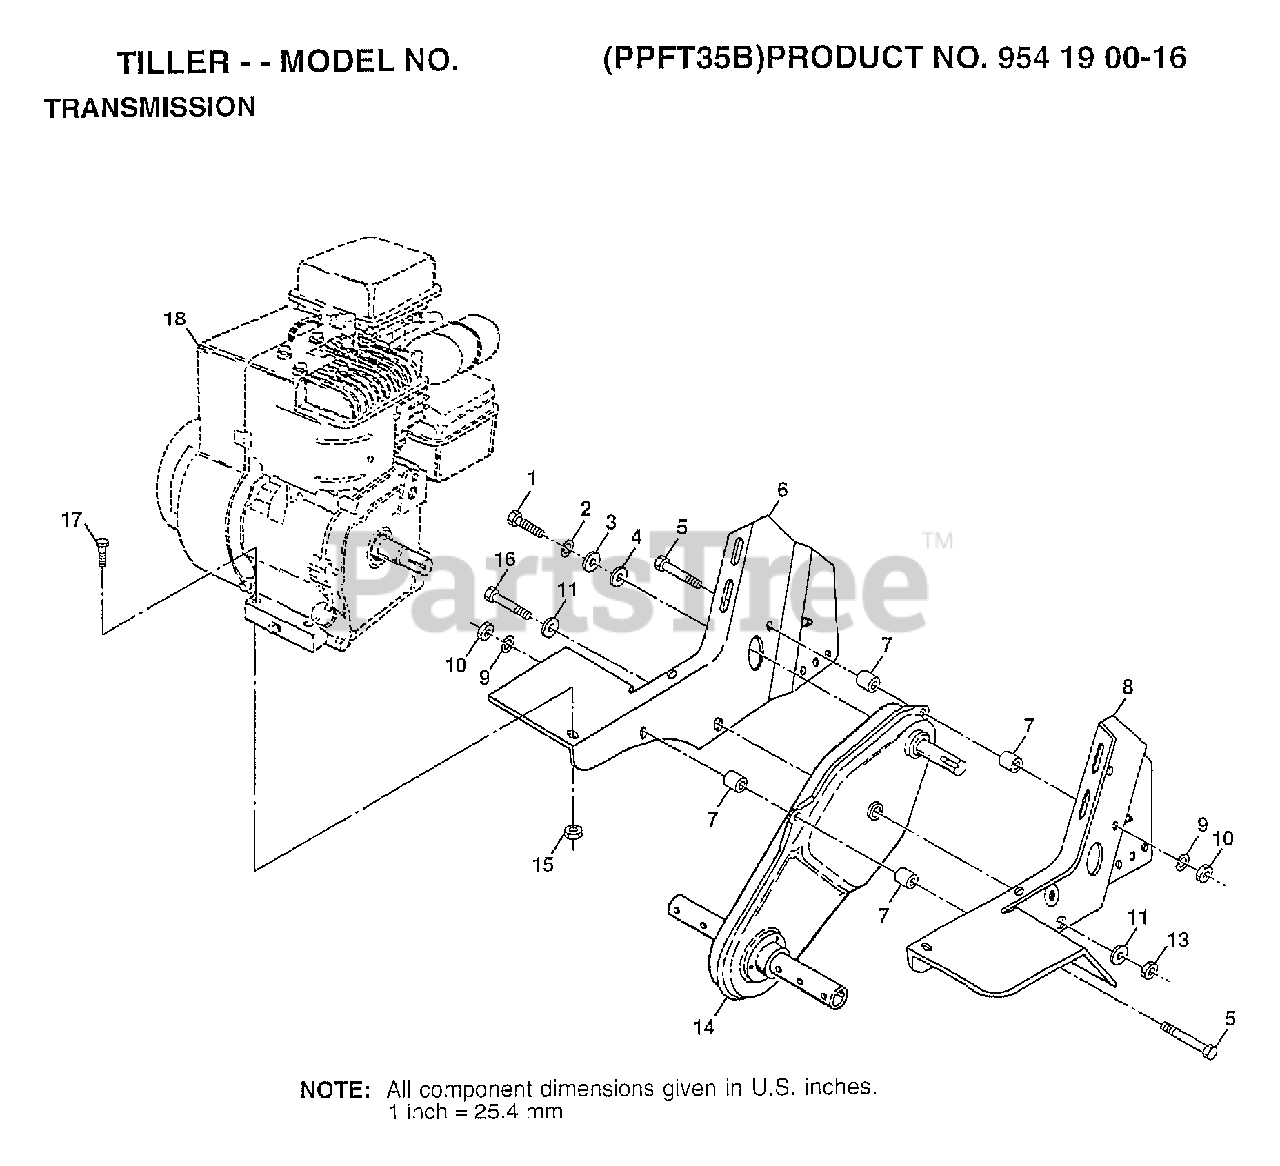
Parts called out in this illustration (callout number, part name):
1	BOLT
2	LOCKWASHER
3	WASHER
4	WASHER
6	ENGINE BRKT RH
7	SPLIT SPACER RT
8	ENGINE BRKT LH
9	LOCKWASHER
10	NUT.HEX.5/16-18
11	WASHER
13	NUT
16	BOLT HEX 3/8-16
17	BOLT.HEX.5/16-1.5
